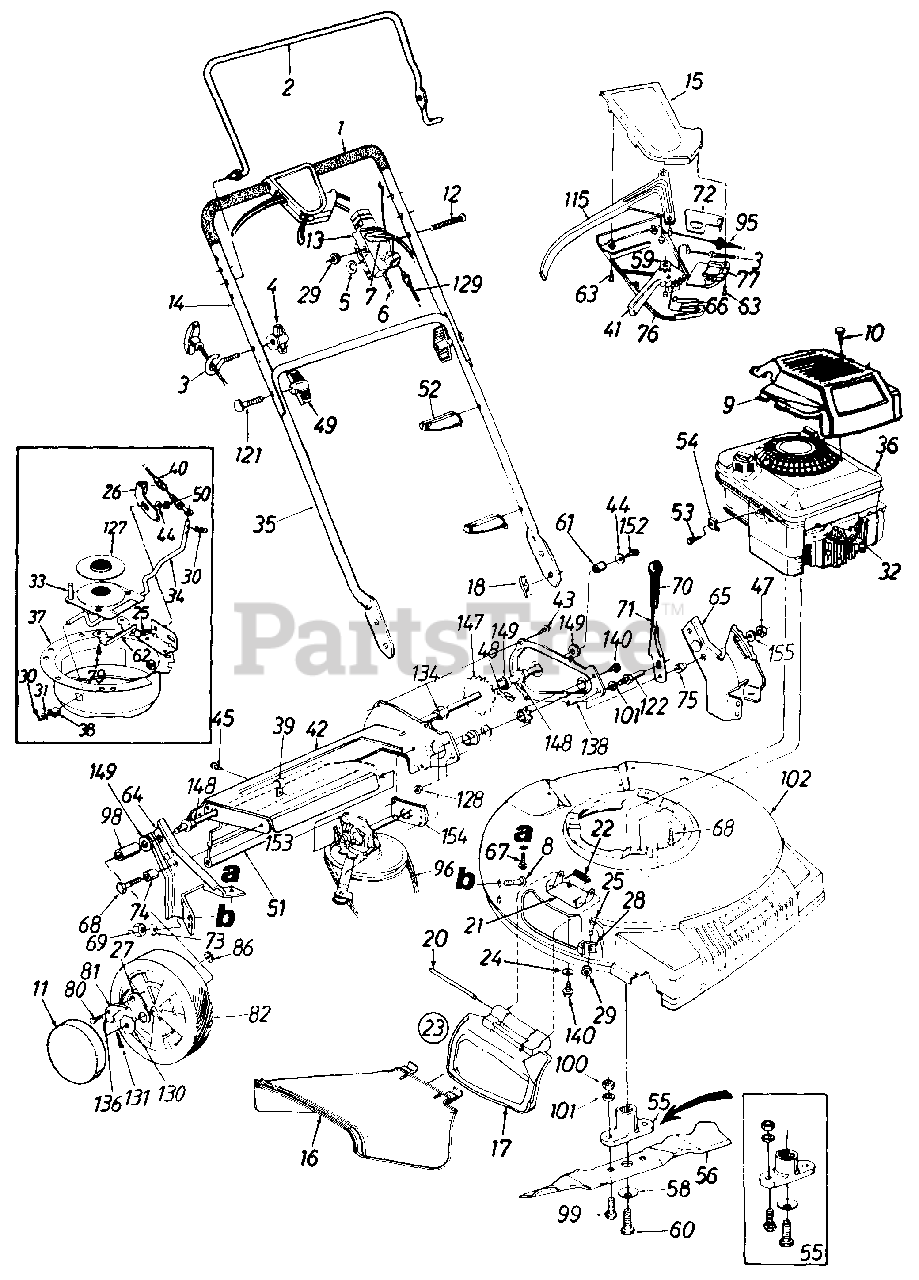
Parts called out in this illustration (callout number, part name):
1	Grip
2	Control Handle
4	Wing Nut 1/4-20 Thd.
5	Curved Spring Wash. .66" I.D.
6	Throttle Wire - 55" Lg.
7	Throttle Lever
8	Carriage Bolt 5/16-18 x .62" Lg.
9	Engine Shroud
10	Hi-Lo Screw #10 x 1.25" Lg.
11	Hub Cap
12	Oval C-Sunk Mach. Scr.
13	Throttle Body
15	Upper Control Housing
16	Side Chute Deflector
17	Mulch Plug
18	Internal Cotter Pin 5/16" Dia.
20	Hinge Pin
22	Torsion Spring
23	Mulch Plug Ass'y. Comp.
24	Bell-Wash. .265" I.D. x .75" O.D.
25	Carriage Bolt 1/4-20 x .5" Lg.
30	Cotter Pin 3/32" Dia. x .75"
31	Fl-Wash. .328" I.D. x .68"
32	Spark Plug Insulator
33	Lower Pulley Half Ass'y.
34	Shift Rod
36	Engine - 5 H.P.
40	6 Spd. Cable
41	6 Spd. Shift Lever
44	Bell-Wash. 1/4" I.D.
45	Truss Mach. B-Tap Scr. #10 x .5"
47	Hex Patch L-Nut 3/8-24 Thd.
48	#48 Chain .500" Pitch x 38 Links
49	Hand Knob
50	Hex L-Nut 1/4-20 Thd.
51	Rear Flap 3.75" x 17.5" Lg.
52	Cable Tie
53	Hex Wash. Hd. Scr. #10-32 x .62" Lg.
54	Casing Clamp
55	Blade Adapter Kit
56	21" Mulching Blade
58	Bell-Wash. .47" I.D. x 1.14" O.D.
59	Gear Insert
60	Hex Bolt 7/16-20 x 2.5"
61	Spacer .513" I.D.
67	Hex B-Tap Scr. 5/16-18
68	Hex TT-Tap Scr. 3/8-16
69	Hex Nut 5/16-18 Thd.
71	Height Adj. Lever
72	6 Spd. Rack Cable Brkt.
73	Bell-Wash. 5/16" I.D.
74	Spacer .383" I.D.
75	Shld. Spacer .5" Dia.
76	Lower Control Housing
77	Cable Mounting Cap
79	Hex Wash. Hd. Tap Scr. 1/4-20 x .38" Lg.
80	Shld. Scr. .342" Dia. x .268
81	Pawl
82	Wheel Ass'y. Comp.
86	Weld Top L-Nut 1/4-20 Thd.
95	S.P. Cable
96	"V"-Belt
98	Sleeve .526" I.D.
99	Hex Bolt 3/8-24 x 1.0" Lg.
100	Hex Nut 3/8-24 Thd.
101	L-Wash. 3/8" I.D.
102	21" Deck Ass'y.
115	Control Lever
121	Curved Hd. Bolt 5/16-18 x 2" Lg.
122	Shld. Pin 1.43" Lg.
127	Pulley Half - Serrated
128	Hex Jam Nut 3/8-24 Thd.
129	Control Cable - 39"
130	Ratchet Wheel 1.62" O.D.
131	Cotter Pin 1/8" Dia. x 1"
134	Hex Flange Bearing
136	Spring - Nylon
147	Rear Shaft Ass'y. 21.44" Lg.
148	Hex Flange Brg. .506" I.D.
149	Fl-Wash. .531" I.D. x .930"
152	Hex Bolt 1/4-20 x .62" Lg. (Grade 5)
153	Transmission Comp.
155	Fl-Wash. .385" I.D. x .87" O.D.
